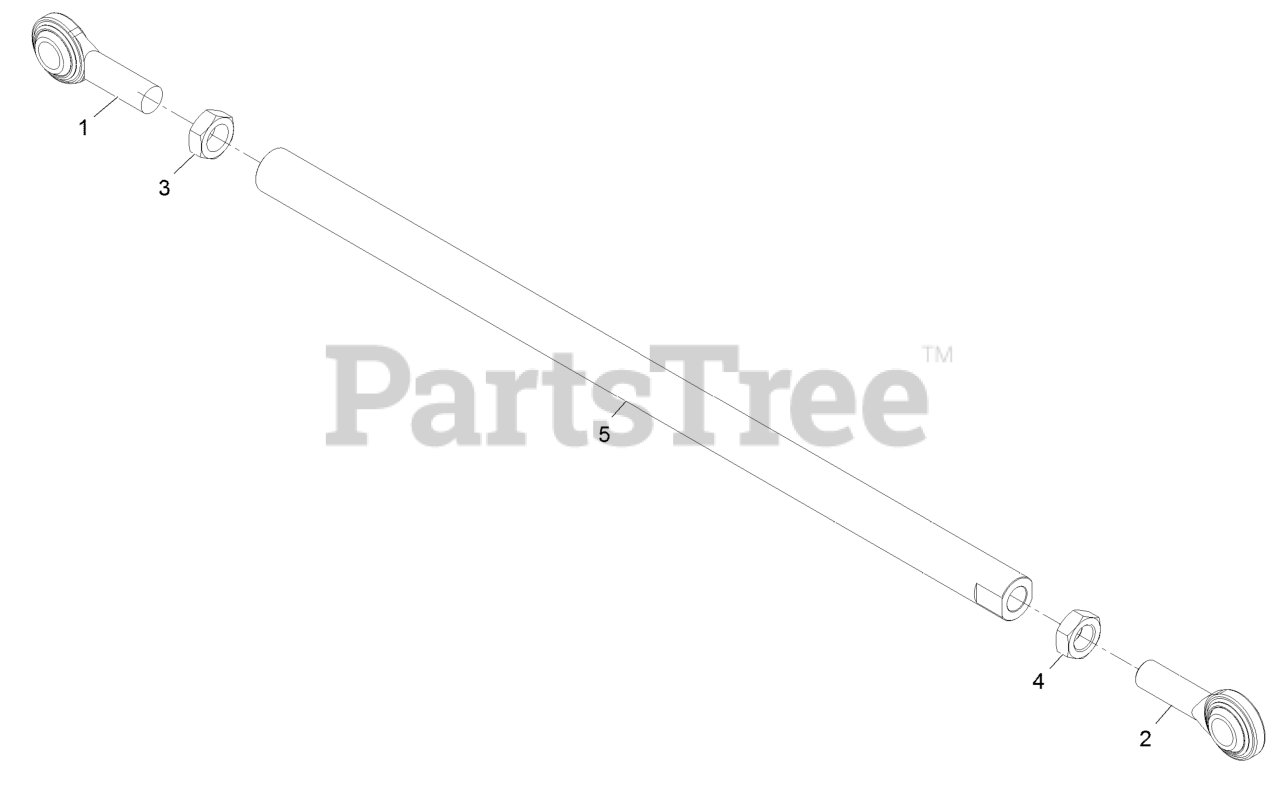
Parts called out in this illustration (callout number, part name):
1	BALLJOINT-SPHERICAL
2	BALLJOINT-SPHERICAL
3	NUT-JAM
4	NUT-JAM
5	LINK-HEIGHT OF CUT
